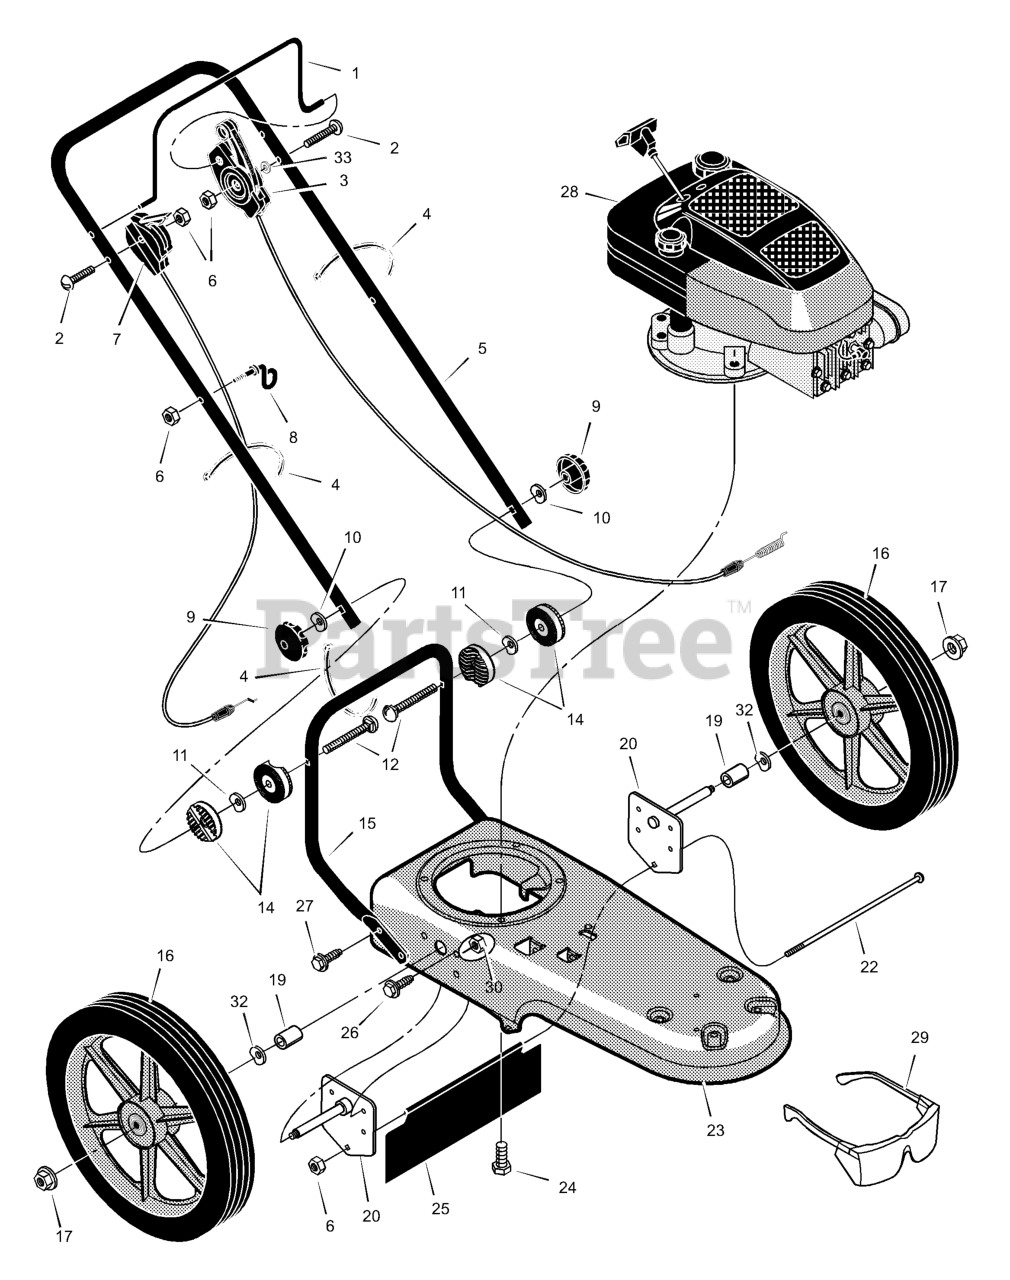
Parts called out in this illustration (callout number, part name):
1	Lever, Stop
3	Cable, Control Latching
4	Tie, Cable
6	Nut
7	Control, Throttle
8	Guide, Rope
9	Knob, Handle
11	Washer, Spring
14	Pivot, Handle
15	Handle, Lower
16	Wheel & Tire
17	Nut, Axle
20	Assembly, Axle & Bracket
22	Bolt, Carriage
23	Frame, Trimmer
25	Shield, Trailing
26	Bolt
28	Engine
29	Glasses, Safety *
30	Nut
32	Washer, Spring
33	Spacer, PM .26x.5x.2
